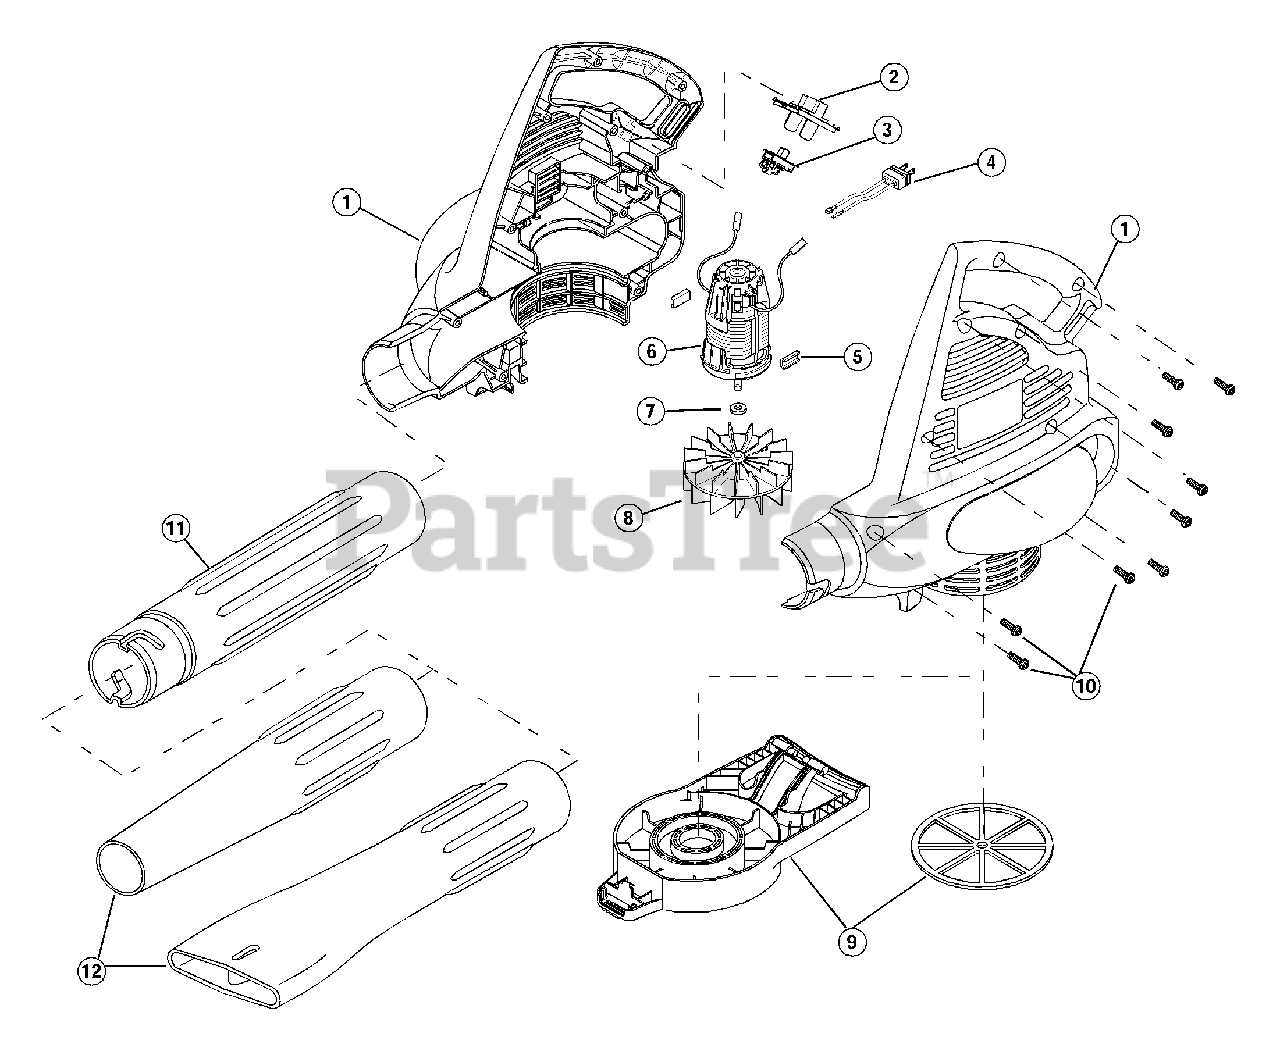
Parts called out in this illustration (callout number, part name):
1	Housing Set
2	Switch Cover
4	Power Cord
5	Motor Pad
8	Impeller
9	Inlet Cover
10	Screw (11 Pack)
11	Blower Tube
